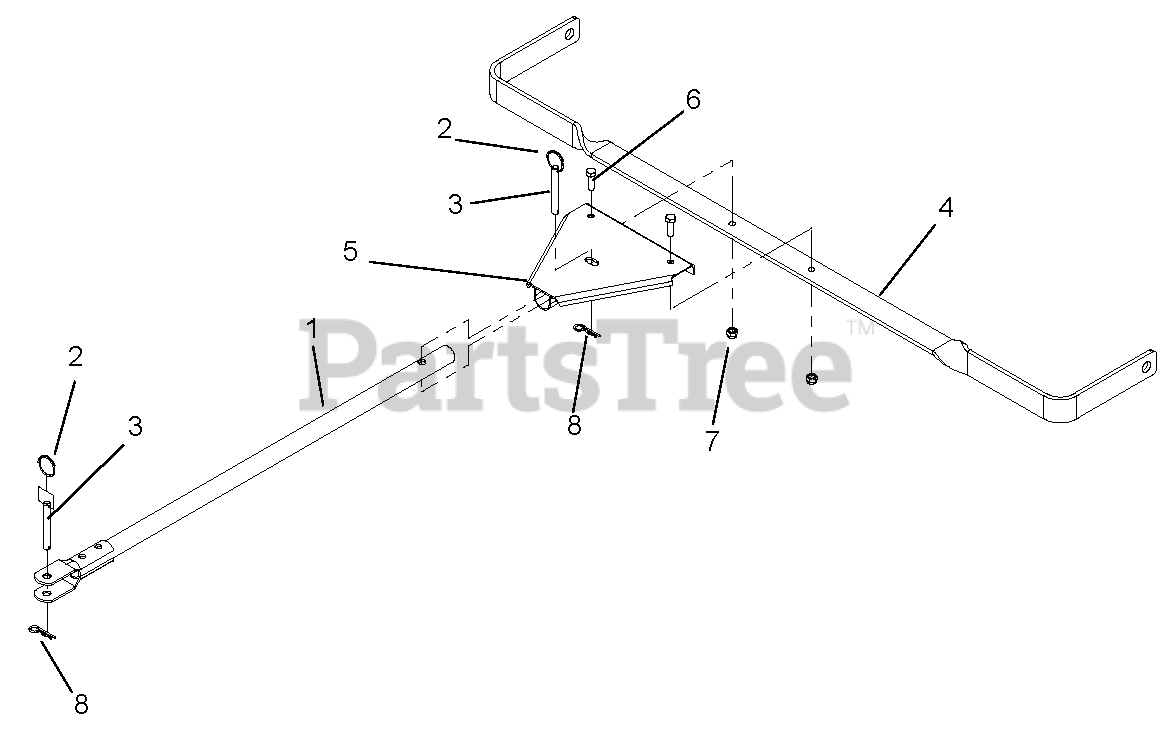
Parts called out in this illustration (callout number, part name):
1	Tongue Weldment
2	Ring, Locking
3	Pin, Hitch
5	Hitch Plate Weldment
6	Bolt, Hex .31-18 x 1.00 Gr 5 YWZC
7	Nut, Nylok .312-18 YWZC
8	Pin, Cotter .09 x 1.50 YWZC
